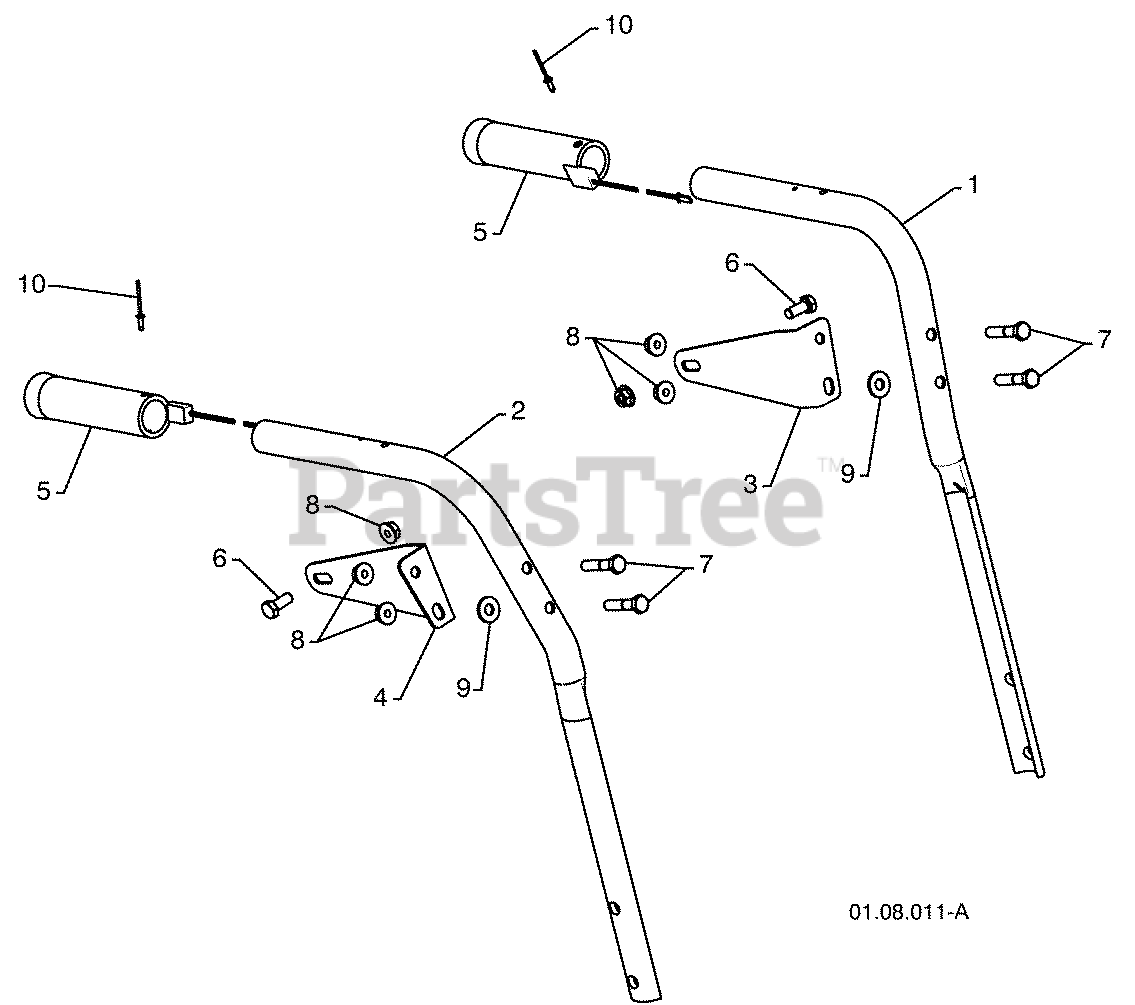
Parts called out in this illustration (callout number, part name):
1	PLOW HANDLE LH
2	PLOW HANDLE RH
3	PANEL BRACKET LH
4	PANEL BRACKET RH
5	HEATED HANDLE GRIP
6	SCREW 5/16--18 X .750
7	SCREW 5/16--18 X 1.50
8	NUT 5/16--18
10	POP RIVET 1/8
